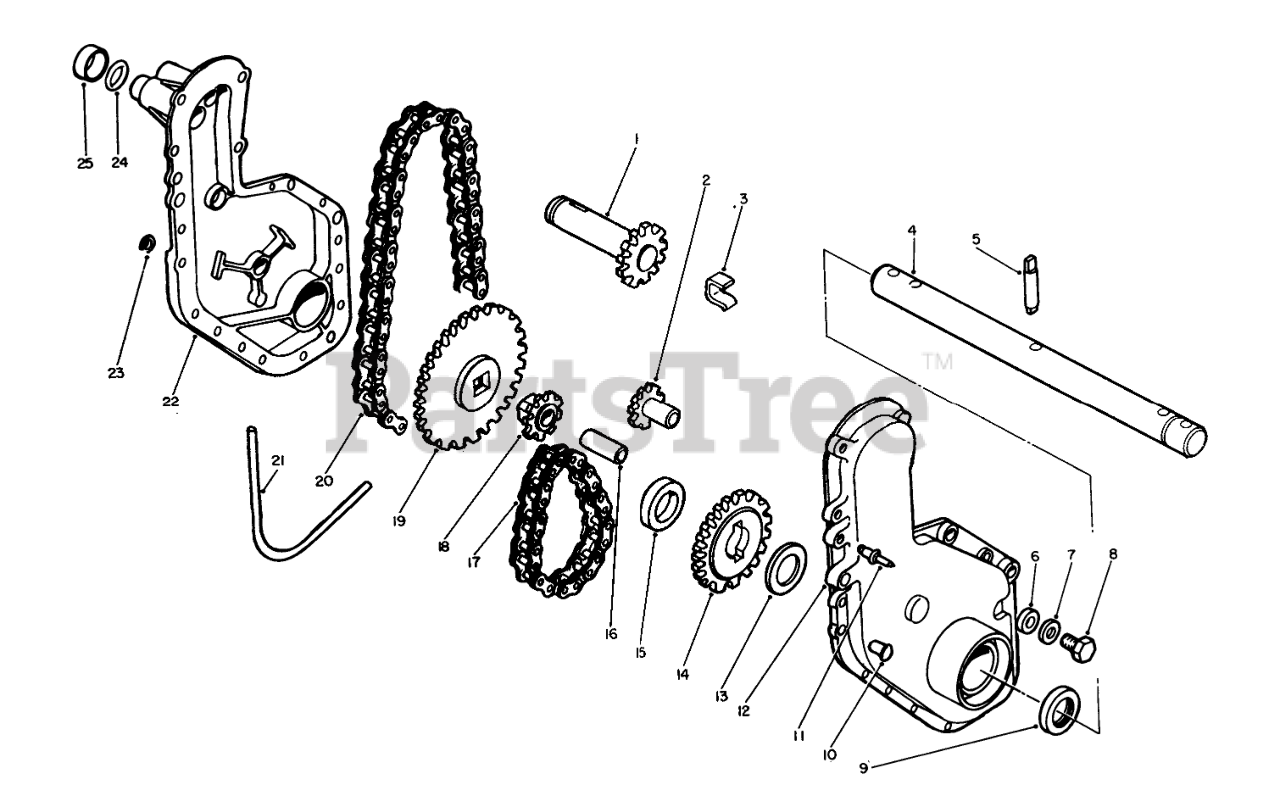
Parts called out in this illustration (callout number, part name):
1	Input Shaft
2	Idler Sprocket-9 Tooth
3	"U" Clip
4	Axle
5	Drive Pin
6	Nylon Washer
7	WASHER-PLAIN
8	SCREW-HH
9	Seal
10	Rivet
11	Pop River
12	Chain Case R.H.
13	Washer
14	Sprocket-27 Tooth
15	Washer
16	Shaft-Sprocket
17	#35 Roller Chain
18	Sprocket-10 Tooth
19	Sprocket
20	Chain-Upper
21	Gasket
22	Chain Case-L.H. w/Bearing
23	WASHER-PLAIN
24	O-Ring
25	Seal Cup
